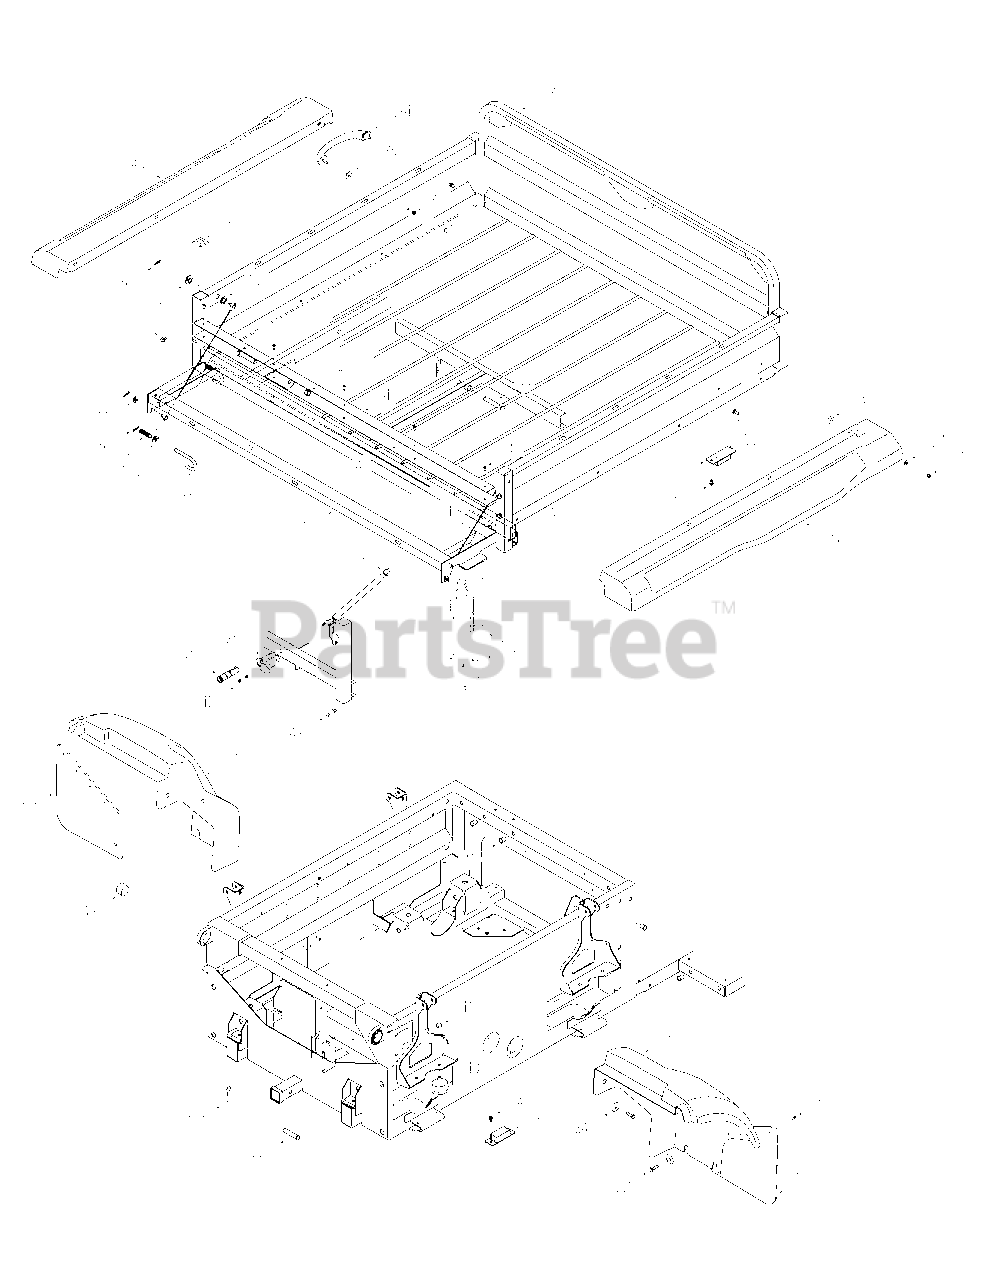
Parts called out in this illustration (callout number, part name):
1	Tailgate Assembly
2	Bed Assembly
3	Screw, Self-tapping, 1/4-20 x 0.500
4	Flat Washer,.271 x.630 x.065
5	Cotter Pin,.072 Dia x 1.13
7	Bumper, Extension Suspension
8	Compression Spring, .406 x .531 x 1.75 LG
9	Bumper, .62Dia x .3
10	Washer, Flat, .64 ID x 1.0 x .12
11	Washer, Flat, .344 x .750 x .120
12	Washer, Flat,.407 x.812 x.135
13	Screw, Hex, 1/2-13 x 2.5
14	Cable, LIft 16.16 LG
15	Handle, Deck Release
16	Spacer, Shoulder .625 Dia x .324 Dia
17	Cotter Pin
18	Electric Actuator, 6" stroke
19	Nut, Acorn 1/4-20 w/o Lock
20	Nut, Hex Lock, 1/4-20
21	Nut, Insert 5/16-18
22	Clevis Pin, .5" dia. x 2.25" long
23	Plug Receptacle, 12V/15A
24	Handle, Bag w/Screw
25	Power Receptacle, 12V/15A
26	Washer, Flat .265 x .938 x .120
27	Harness Jumper
28	Hex Lock Nut, 1/2-13
29	Hex Screw, 1/4-20 x.75
30	Fender, Rear RH, Red
31	Fender, Rear LH, Red
32	Rubber Washer,.310 x 1.0 x.125
33	Hex Screw, 5/16-18 x 1.0
34	Bell Washer,.39 x 1.38 x.062
35	Bed Skirt Panel, LH, Red
36	Bed Skirt Panel, RH, Red
37	Rear Mud Flap
38	Pop Rivet,.188
39	Rubber Bushing, Bed Pivot
40	Bumper, Compression Suspension
41	Hex Lock Nut, M10-1.25
42	Screw, #10-24 x .500
43	Hex Nut, 10-24
44	Clevis Pin, .5" dia. x 3" long
47	Tail Gate Seal Strip
